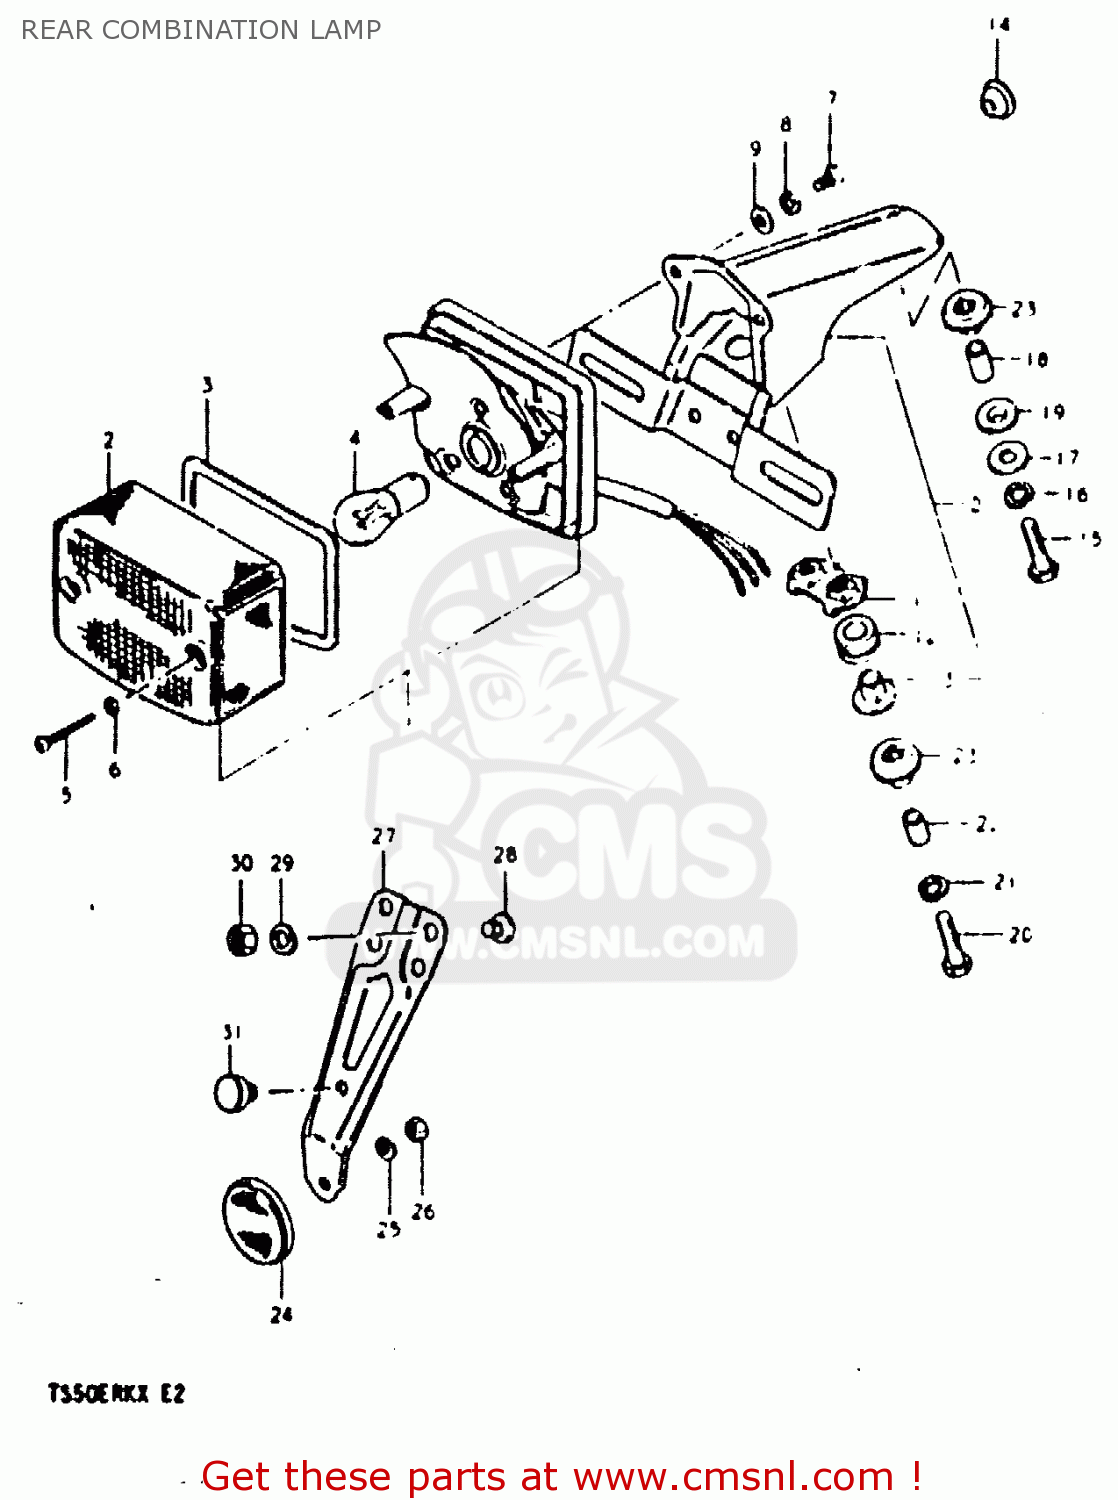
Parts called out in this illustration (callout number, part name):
1	LAMP UNIT, TAIL
2	LENS
3	GASKET (NAS)
4	BULB (6V,21/5W)
5	SCREW
6	GASKET (NAS)
7	SCREW
8	LOCK WASHER
9	WASHER
10	BRACKET ASSY
11	PLATE
12	CUSHION
13	SPACER
14	GROMMET
15	BOLT
16	LOCK WASHER
17	WASHER
18	SPACER
19	CUSHION
20	BOLT 6X40
21	LOCK WASHER
22	SPACER (6.8X10X11.5)
23	CUSHION
24	REFLEX REFLECTOR,RR
25	LOCK WASHER
26	NUT
27	BRACKET
28	SCREW
29	LOCK WASHER
30	NUT
31	CUSHION
